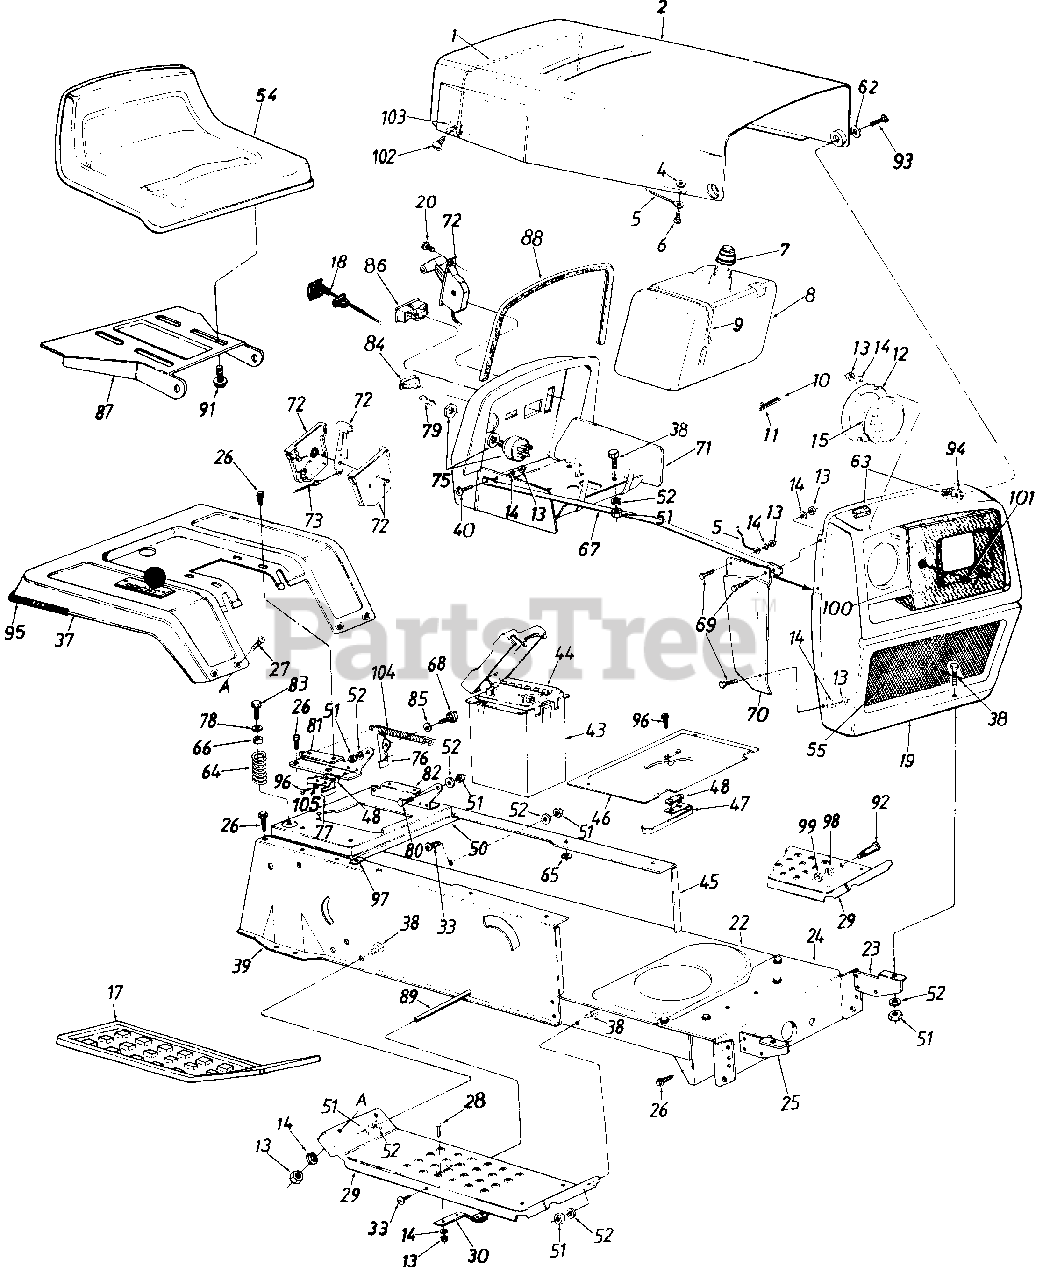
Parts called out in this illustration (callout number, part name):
1	Hood Spring
5	Hood Stop 7" Lg.
6	Pop Rivet
7	Fuel Cap Gauge
8	Fuel Tank
9	Tie Strap
10	Fuel Line
11	Hose Clamp
12	Headlight Retainer
13	Hex Nut 1/4-20 Thd.
14	L-Wash 1/4 I . D .
15	Headlight
17	Foot Pad-L.H.
18	Choke Control 29" Lg.
19	Grille Ass'y.
20	Truss Mach. AB-Tap Scr. #10 x .50" Lg.
22	Lower Frame
23	Grille Mount Brkt.
24	Front Pivot Brkt.
25	Grille Mount Brkt.
26	Hex Wash. Hd. AB-Tap Scr. 5/16 x .75" Lg.
27	Carriage Bolt 1/4-20 x 2.0"
28	Carriage Bolt 1/4-20 x .62"
29	Running Board
30	Blade Brake Ass'y.
33	Truss Mach. Scr. 5/16-18 x .75" Lg.
39	R.H. Side Frame
40	Hex Bolt 1/4-20 x .62" Lg.
43	Battery Box w/Cover
44	12-V Battery
45	L.H. Side Frame
46	Shift Cover
47	Reverse Safety Switch
48	Insulator Nut Plate
50	Hitch Plate
51	Hex Nut 5/16-18 Thd.
52	L-Wash. 5/16" I.D.
54	Seat Ass'y.
55	Grille Insert
62	Washer .39" I.D. x .62" O.D.
63	Foam Strip 3/8 x 1-1/8 x 11/2
64	Compression Spring
65	Ext. L-Wash. 5/16" I.D.
66	Bushing
67	Grille Support Rod-R.H.
69	Truss Hd. Scr. 1/4-20 x .75"
70	R.H.-Grille Side Panel
73	Throttle Control Wire
75	Ignition Switch
76	Seat Lift Bracket
77	Spring Switch
78	Fl-Wash. .344" I.D.
79	Ignition Key
80	Shld. Bolt .437" Dia. x .162"
81	Seat Pivot Brkt. Support-R.H.
82	Seat Pivot Brkt. Support-L.H.
83	Hex Hd. Tap Scr. 5/16-18 x 1 " Lg.
84	Light Switch
85	Spr-Wash. .445" I.D. x .75" O.D.
86	Ammeter
87	Seat Pivot Bracket
88	Molding Strip 27" Lg.
89	Running Board Rod
91	Hex Wash. Hd. Tap Scr. 3/8-16 x .75" Lg.
92	Shld. Bolt .5" Dia. x .84"
93	Shld. Bolt .375 Dia. x .125
94	Hex L-Nut 1/4-28 Thd.
95	Trim Strip-81"
96	Hex Wash. Hd. AB-Tap Scr. #8 x .50" Lg.
97	Speed Nut #10Z
98	L-Wash. 3/8" I.D.
99	Hex Nut 3/8-16 Thd.
100	Bezel
101	Oval C-Sunk Mach. Scr. 1/4-20 x 1.5" Lg.
102	Self-Tap Scr. .5" Lg.
103	Hood Spring Retainer
104	Extension Spring 5.31" Lg.
105	Fiber Washer
